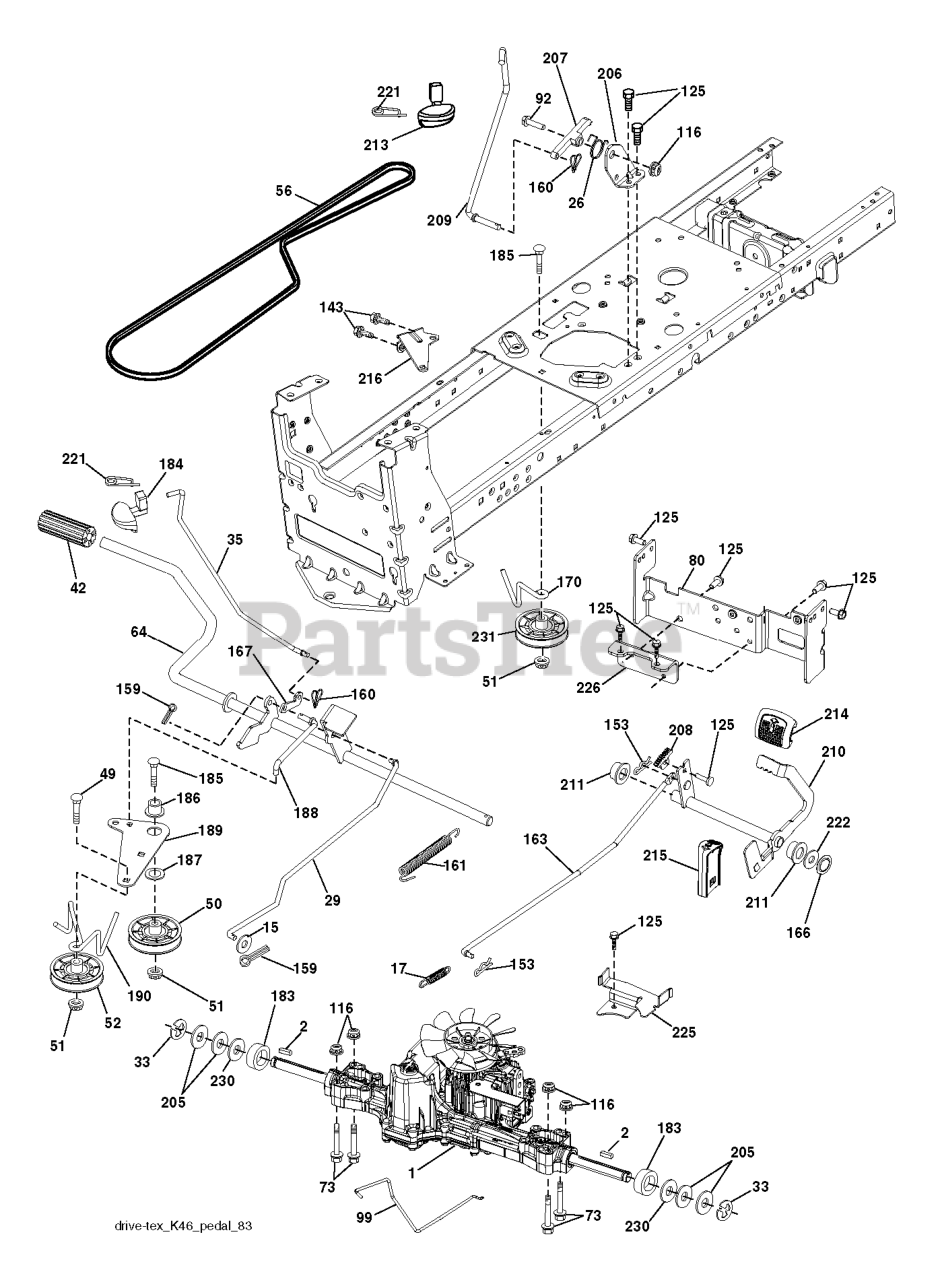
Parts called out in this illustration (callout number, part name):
2	SQUARE KEY
15	WASHER
17	SPRING.BRAKE.K46.GREEN
26	SPRING.RETURN.CRUISE
29	ROD.BRAKE.K46
35	ROD .BRAKE. PARKING. GT. HUSQ.
42	PEDAL COVER T
50	IDLER.FLAT.910.OFFSET
51	NUT LOCK FLG 3/8-16 UNC
52	IDLER.V-GROOVE.910.OFFSET
56	V-BELT.MOWER.92.40.42/K46
64	SHAFT.ASM.PEDAL.BRK.CNTR
80	STRAP TORQUE.ASM.K46/18"TEX
92	BOLT
99	ROD.SPRING.BYPASS.K46.LT.Z
116	NUT LOCK HEX FLANGE 5/16-18
125	SCREW
143	Screw 5/16-18 x 1/2 Hex, Self Tapping 5/16-18 x 1/2
153	RETAINER M
159	COTTER PIN
160	RETAINER CLIP
161	SPRING, RETURN LT
163	ROD.CONTROL.K57R.K46
166	NUT.PUSH.625
167	LATCH.BRAKE.SPRING
170	KEEPER.V-IDLER.CENTER.
183	SPACER AXLE
184	HANDLE.PARKG.BRK.HUSQ X667
186	SPACER.RETAINER
187	WASHER 12/32X2X10GA
188	RP.LINK.CLUTCH.GROUND.DRIVE
189	BELLCRANK.GROUND.DRIVE.TEX.
190	KEEPER.BELLCRANK.DRIVE
206	BRKT.MOUNT.LATCH.CRUIS
207	LATCH.CONTROL.CRUISE
208	GEAR.SECTOR.CONTROL.CR
209	ROD.CONTROL.CRUISE.GT.
210	ROCKER.ASM.PEDAL.CONTR
211	BEARING.NYLON
213	KNOB.CONTROL.CRUSIE.HU
215	PEDAL.REVERSE.TEX.GT.4
216	BRACKET.PULLEY.IDLER.W/TEX
221	RETAINER.SPRING.CLIP.H
222	WASHER 21/32 X 1-1/4 X 10 GA.
225	KEEPER.BELT.TRANSAXLE.K46
226	BRACKET.MOUNT.TORQUE.K46.TLT
230	WASHER.HARDENED
231	IDLER.V-GROOVE.910.OFFSET
